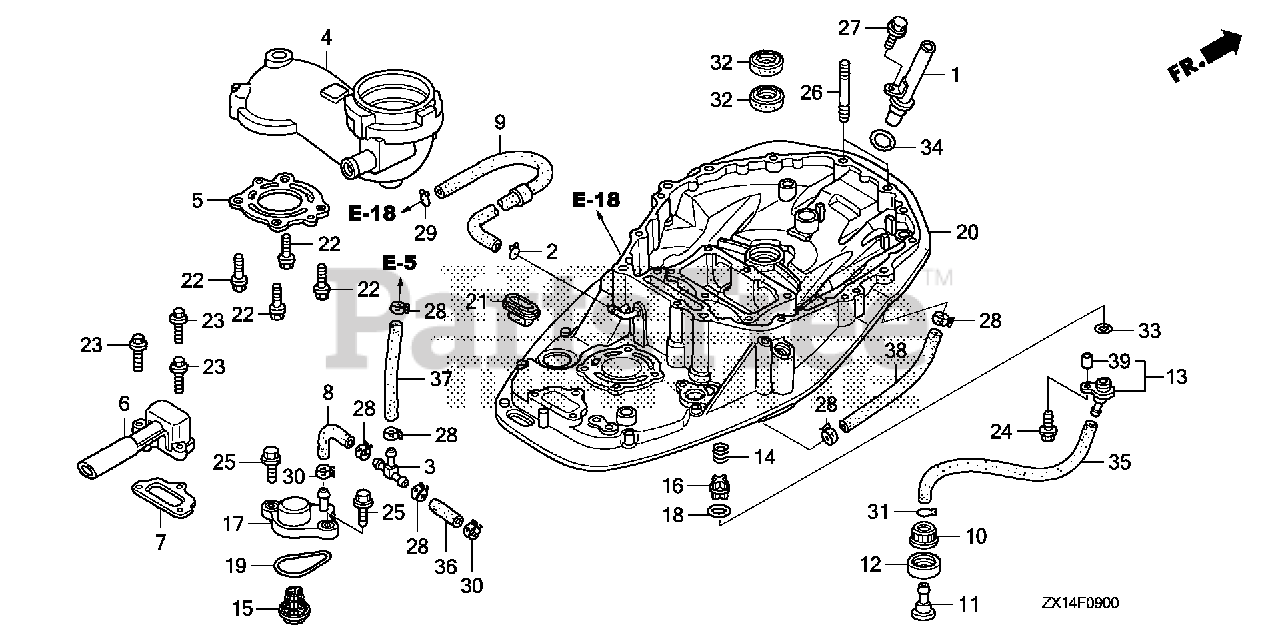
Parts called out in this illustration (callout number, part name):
1	PIPE, OIL LEVEL
2	CLIP, TUBE (ENGINE NO.)
4	GUIDE, EX. *NH8* (DARK GRAY)
5	GASKET, EX. GUIDE
6	PORT, IDLE EX.
7	GASKET, IDLE EX. PORT
8	TUBE, WATER RELIEF
9	TUBE F, WATER
10	NUT, WATER MOUTH
11	JOINT, WATER HOSE
12	SEAT, WATER MOUTH
13	COVER, FLUSH VALVE
13	COVER, FLUSH VLV
14	SPRING, FLUSH VALVE
15	VALVE ASSY., RELIEF
16	VALVE, FLUSH
17	COVER, RELIEF VALVE
18	GASKET, FLUSH VALVE
19	O-RING, THERMOSTAT COVER
20	CASE, MOUNT *NH8* (DARK GRAY)
21	RUBBER, MOUNT CASE SEAL
22	BOLT, FLANGE (8X30)
23	BOLT, FLANGE (6X25)
24	BOLT, FLANGE (6X16)
24	BOLT, FLANGE (6X20) (ENGINE NO.)
25	BOLT, FLANGE (6X22)
26	BOLT, STUD (10X55)
27	BOLT, FLANGE (6X12)
28	CLAMP, TUBE (D10.5) (ENGINE NO.)
29	CLIP, TUBE (B12)
30	CLAMP, TUBE (D10.5) (ENGINE NO.)
31	CLIP B1, TUBE
32	SEAL, WATER (22X35X7)
33	O-RING (16MM)
34	O-RING (11.5X3.5)
35	BULK HOSE, FUEL (8X1000) (95001-80001-(95001-80001-60M)
36	BULK HOSE, VACUUM (7X3000) (7X550)
37	BULK HOSE, VACUUM (7X3000) (7X550)
38	BULK HOSE, VACUUM (7X3000) (7X550)
39	COLLAR, DISTANCE (6.5X11X7.5)
